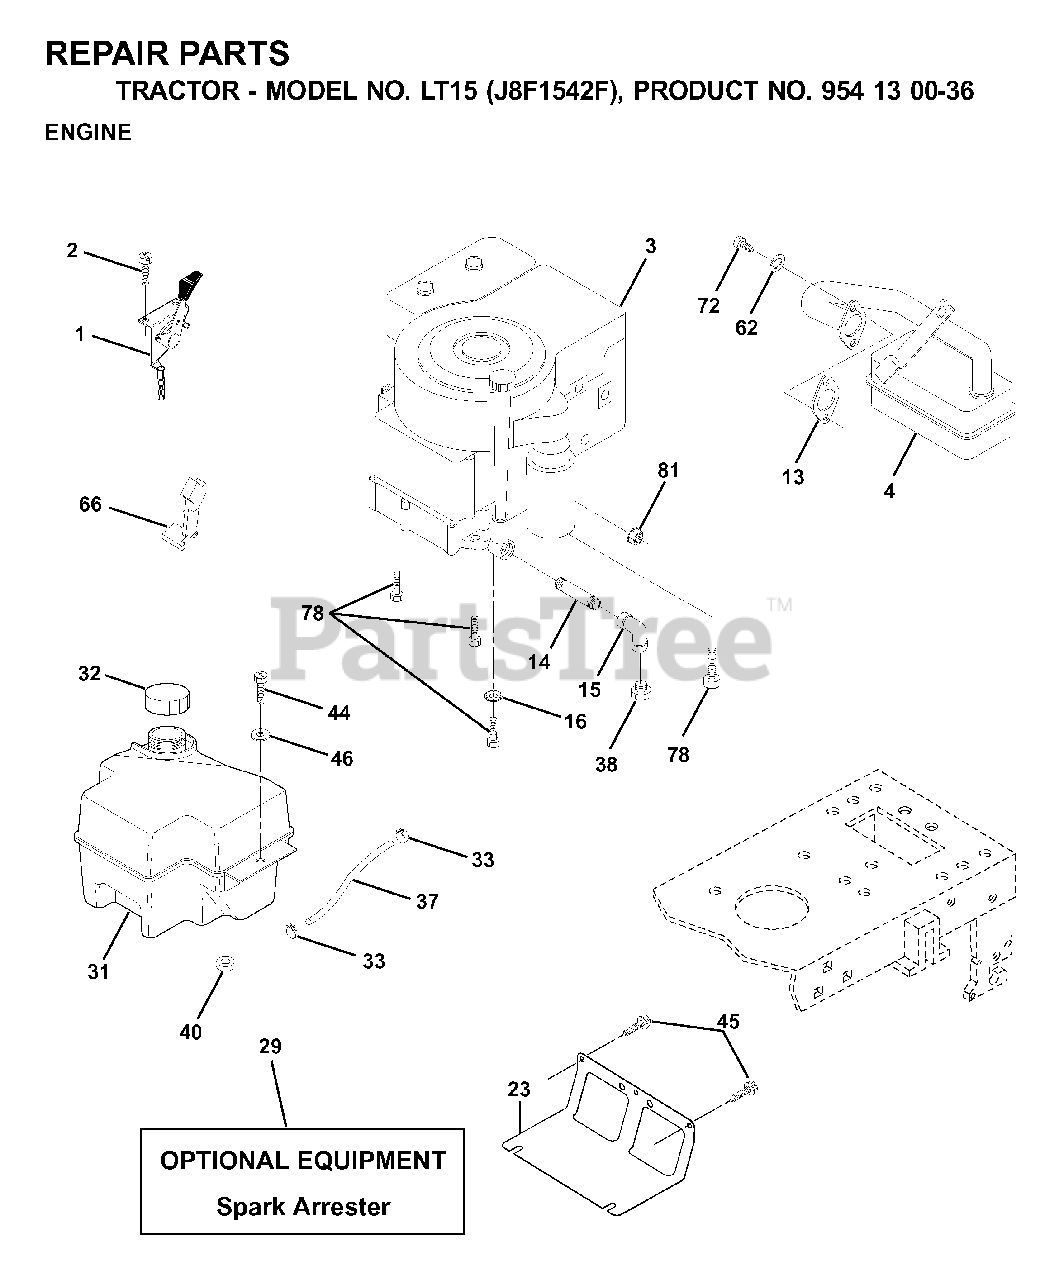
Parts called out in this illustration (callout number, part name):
1	CONTROL
2	SCREW LT
13	REPL BY 532 27 22-93
15	ELBOW
16	LOCKWASHER
23	SHEILD.BROWNING.DBR.GUARD
29	ARRESTER SPARK (OPTIONAL)
31	FUEL TANK
32	FUEL CAP
33	HOSE CLAMP
37	LINE.FUEL.20
40	GROMMET T
44	SCREW HEX CRT
45	SCREW 3/8-16X3/4
62	LOCKWASHER
66	STOP THROTTLE
72	SCREW
78	SCREW.3/8-16
81	NUT FLANGE 1/4-20 STARTER NUT
